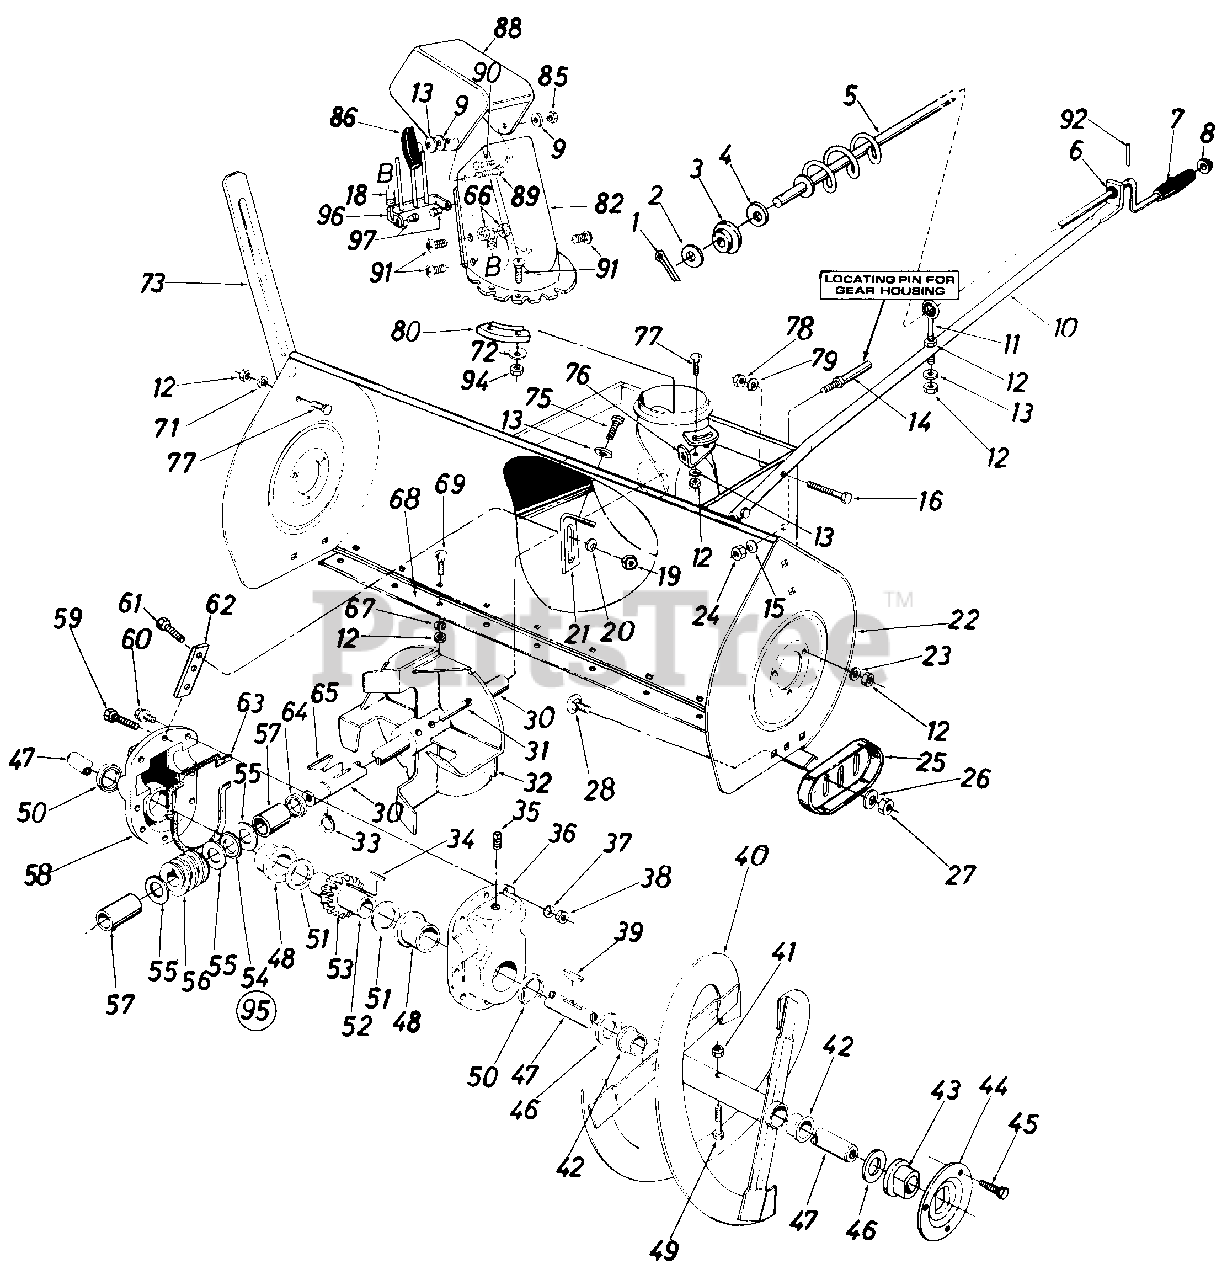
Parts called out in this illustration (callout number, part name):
1	Cotter Pin
2	Fl.-Wash..39" I.D, x .62" O.D.
3	Plastic Bushing
4	Fl.-Wash..385" I.0. x .62" O.D.
5	Chute Crank Ass'y.
6	Plastic Bushing
7	Knob (Black)
8	Push Nut 3/8" Rod
9	Fl.-Wash..344" I.D. x 1.25" O.D.
10	Chute Crank Support Tubing
11	Eyebolt
12	Hex Nut 5/16-18 Thd.
13	Bell.-Wash..345" I.D. x .88" O.D.
14	Stud 3/8-16 x 2.75" Lg.
15	Bell.-Wash..400" I.D. x .88" O.D.
16	Hex Bolt 3/8-24 x 1.25" Lg."
18	Extension Spring
19	Hex Nut 1/4-28 Thd.
20	Bell.-Wash..265" I.D. x .75" O.D.
22	45" Snow Blower Housing Ass'y.
23	L.-Wash. 5/16" I.D.
24	Hex Jam Nut 3/8-16 Thd.
25	Slide Shoe
26	Bell.-Wash..400" I.D. x .88" O.D.
27	Hex Jam Nut 3/8-16 Thd.
28	Carriage Bolt 3/8-16 x .62" Lg.
30	Blower Axle .875" Dia. x 14.75" Lg.
31	Spring Pin Spir. 5/16" Dia. x 1.75" Lg.
34	#91 Woodr-Key 1/4 x 3/4" Dia. (HDN)
35	Vent Plug
36	Gear Hsg. Half L.H.
37	Spr.-Wash..32" I.D. x .62" O.D.
38	Hex Ins. L.-Nut 5/16-18 Thd.
39	#91 Woodr-Key 1/4 x 3/4" Dia. (HDN)
41	Hex Ins. L.-Nut 5/16-18 Thd.
42	Plastic Bushing
43	Flange Brg. w/flats 1" I.D.
44	Bearing Housing
45	Hex Sems Bolt 5/16-18 x .75" Lg.
46	Fl.-Wash. 1.00" I.D. x 1.75" O.D.
47	Spiral Axle
48	Flange Bearing 1.503" I.D.
49	Shear Bolt 5/16-18 x 1.75" Lg.
50	Oil Seal 1.50" I.D.
51	Fl.-Wash. 1.50" I.D. x 2.00" O.D.
52	Worm Gear Shaft
53	Double Threaded Worm Gear- L.H.
54	Thrust Brg. - .88" I.D. x 1.44" O.D.
55	Fl.-Wash..88" I.D. x 1.4" O.D.
56	Double Threaded Worm-L.H.
57	Sleeve
58	Gear Hsg. Half - R.H.
59	Hex Bolt 5/16-18 x 1.25" Lg.
60	Hex Bolt 5/16-18 x 1.0" Lg. (Grade 5)
61	Hex Bolt 1/4-28 x .75" Lg.
62	Gear Housing Support Plate
63	Rubber Gasket
64	Oil Seal - .875" I.D.
65	#9 Hi-Pro Key 3/16 x 3/4" Dia. (HT)
66	Hex L-Nut 1/4-20 Thd.
67	L.-Wash. 5/16" I.D.
69	Carriage Bolt 5/16-18 x 1.00" Lg.
71	L-Wash. 5/16" 1.D.
72	Fl.-Wash. 1/4" I.D.
73	Guide Blade
75	Hex Wash. Hd. AB Tap Scr. 5/16" x .75" Lg.
77	Carriage Bolt 5/16-18 x .75" Lg.
78	Hex Ins. L.-Nut 3/8-24 Thd.
79	L.-Wash. 3/8" I.D.
80	Chute Flange Keeper
82	Lower Chute
85	Hex Cent. L.-Nut 5/16-18 Thd.
86	Knob Handle
88	Upper Chute
89	Carriage Bolt 5/16-18 x 1.00" Lg.
90	Truss Mach. Scr. 5/16-18 x .75" Lg.
91	Truss Mach. Scr. 1/4-20 x .75"
92	Roll Pin .12" Dia. x .63"
94	Hex Cent. L-Nut 1/4-20 Thd.
95	Gear Box Ass'y.-Comp.
97	Shld. Nut 1/4-20 Thd.
